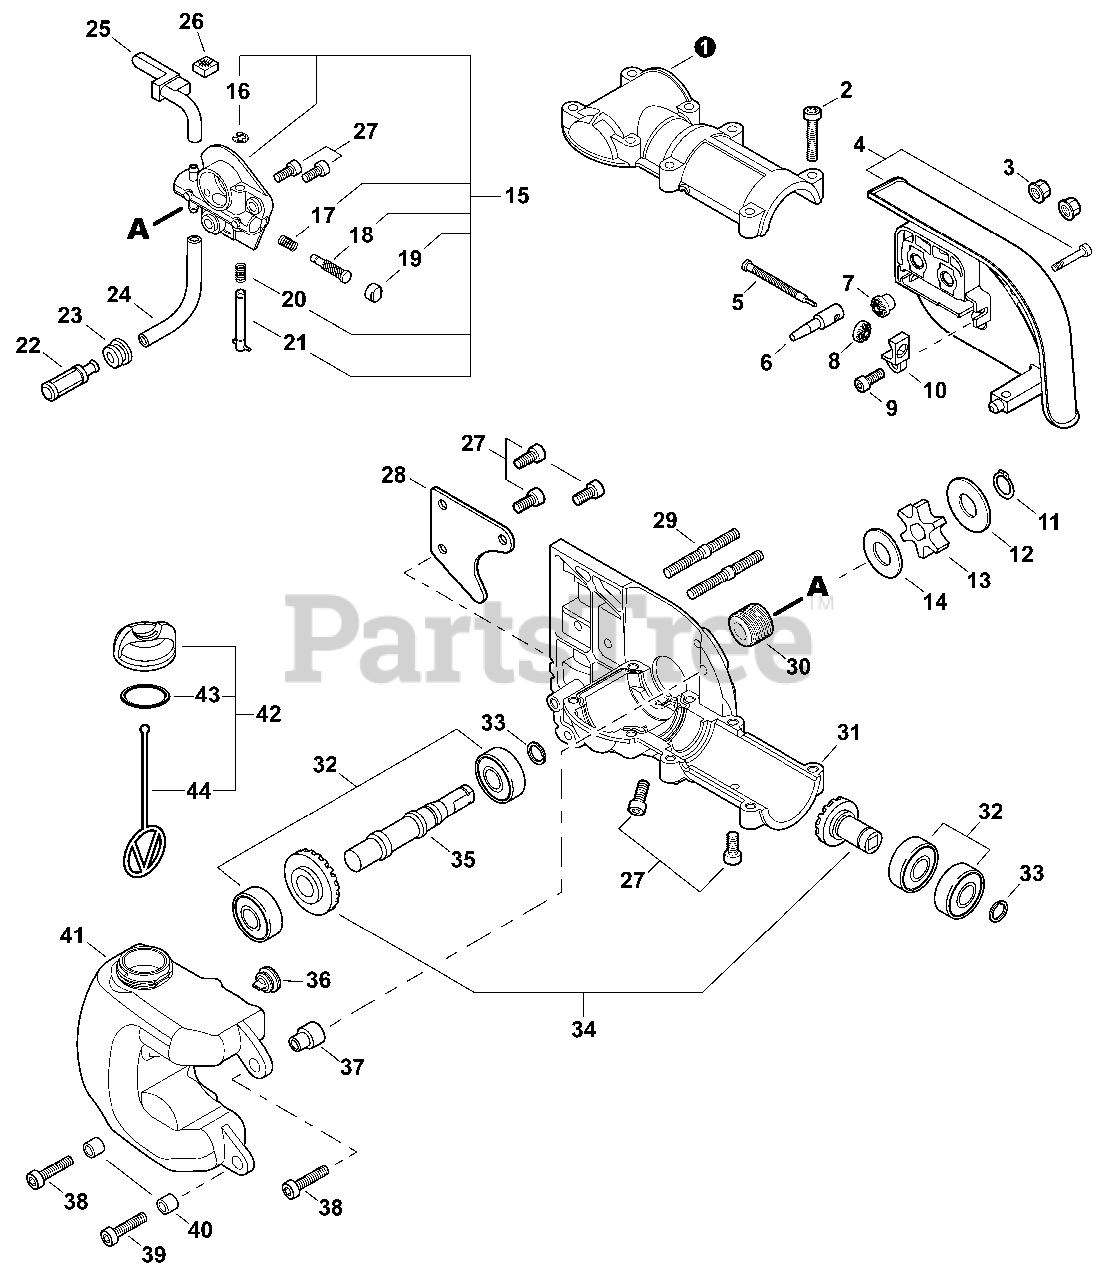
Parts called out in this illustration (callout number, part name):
1	COVER, GEAR CASE
2	BOLT, TORX 5×25
3	NUT, FLANGE M6
4	GUARD, SPROCKET
6	TENSIONER, CHAIN
7	GEAR - 14 TOOTH
8	GEAR - 14 TOOTH
9	SCREW 4
10	COLLAR 8
11	RING, SNAP
12	WASHER 10
13	SPROCKET, DRIVE
14	WASHER 10.2×24.5×1.2
15	AUTO-OILER ASSY
18	PLUNGER ASSY
19	CAP, PLUNGER
21	ADJUSTER, OILER
22	FILTER, OIL
23	GROMMET
24	PIPE 3×6×70
25	PIPE, OIL OUTLET
26	PAD, FOAM
27	BOLT, TORX 5×10
29	BOLT, STUD 6
30	GEAR, WORM
31	CASE, GEAR
32	BEARING, BALL
33	RING, SNAP Ø12
34	GEAR SET
35	SHAFT, GEAR
36	VENT ASSY
37	COLLAR 6
38	BOLT, TORX 5×20
39	BOLT, TORX 5×25
40	SPACER 6.2×7.8×6
41	TANK, OIL
42	CAP ASSY
43	O-RING 18
44	CONNECTOR, CAP L= 60 MM
